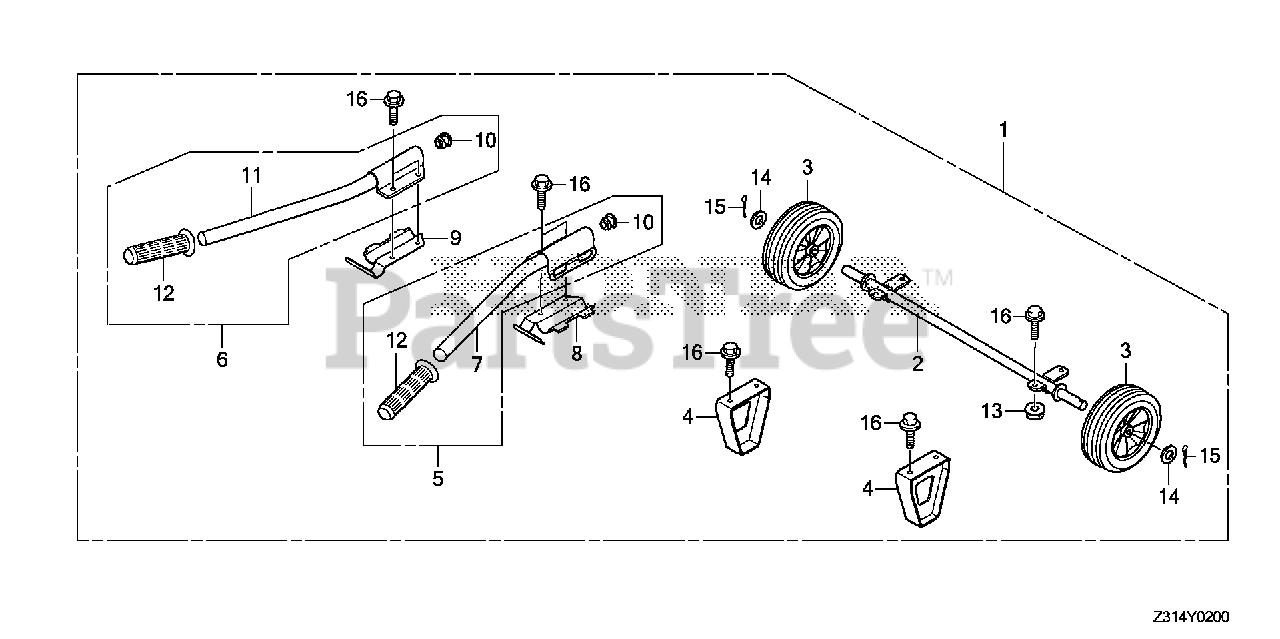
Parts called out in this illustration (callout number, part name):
1	WHEEL KIT (2-WHEELS) *NH105* (MAT BLACK)
2	SHAFT, WHEEL *NH105* (MAT BLACK)
3	WHEEL (254X63.5) (COO)(FOR U.S.A.)
4	STAND *NH105* (MAT BLACK)
5	HANDLE ASSY., R. (UPPER) *NH105* (MAT BLACK)
6	HANDLE ASSY., L. (UPPER) *NH105* (MAT BLACK)
7	HANDLE, R. (UPPER) *NH105* (MAT BLACK)
8	BRACKET, R. HANDLE (LOWER) *NH105* (MAT BLACK)
9	BRACKET, L. HANDLE (LOWER) *NH105* (MAT BLACK)
10	CAP, HANDLE (LOWER)
11	HANDLE, L. (UPPER) *NH105* (MAT BLACK)
12	GRIP, HANDLE
13	NUT, FLANGE (8MM)
14	WASHER, PLAIN (20MM)
15	PIN, SPLIT (4.0X28)
15	PIN, COTTER (4.0X30)
16	BOLT, FLANGE (8X16)
